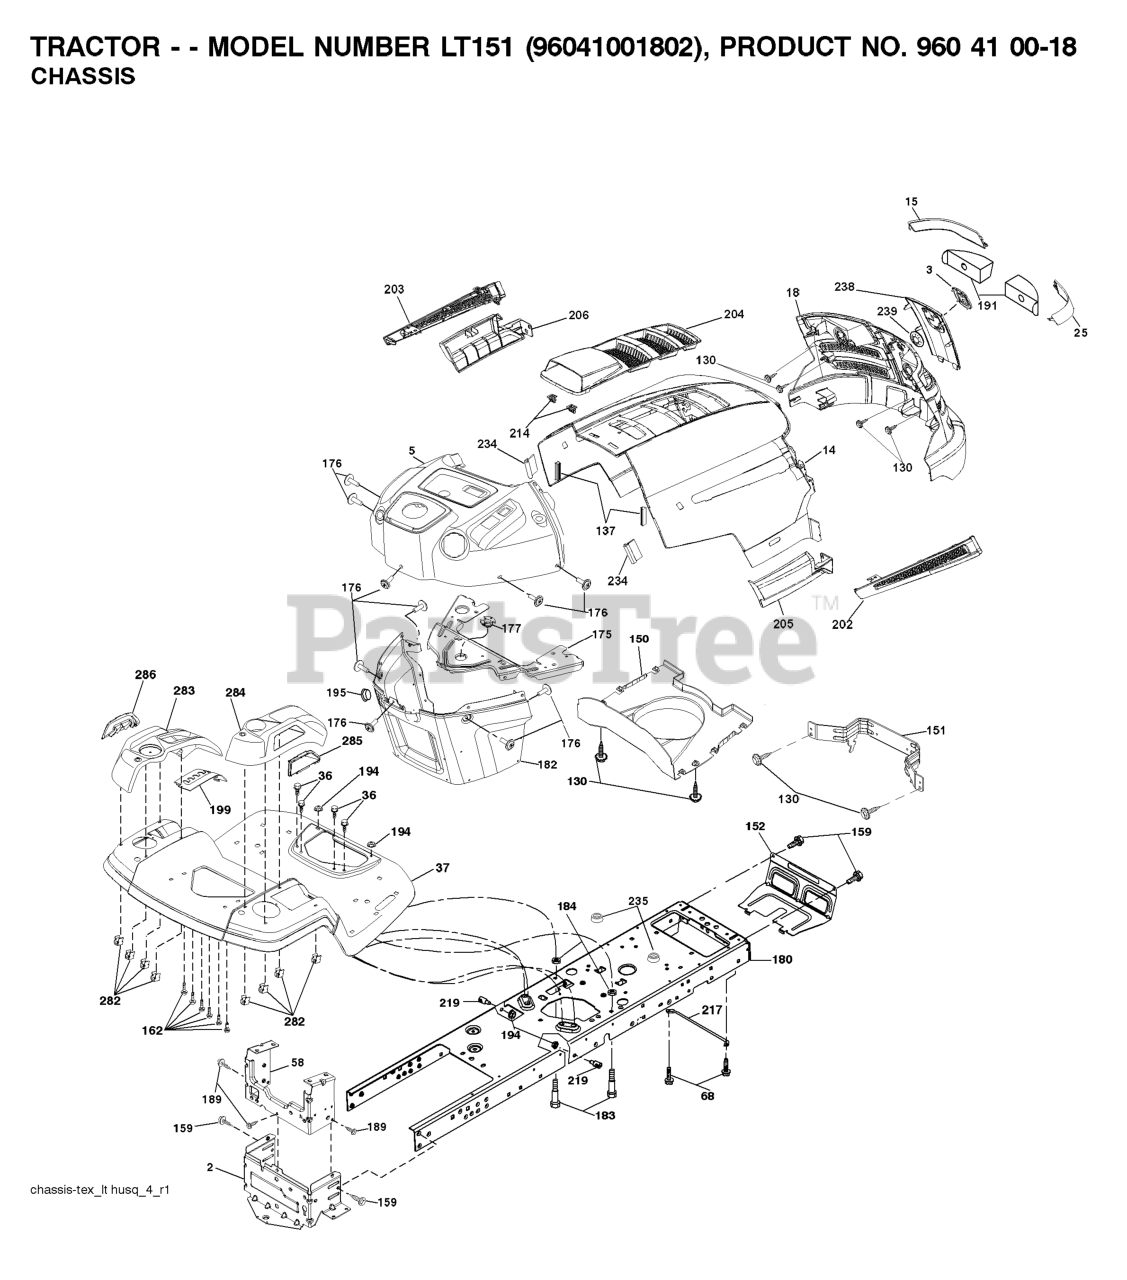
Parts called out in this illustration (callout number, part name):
2	DRAWBAR.UPPER.2PC,LRG.FENDER
3	RP LOGO
5	DASH
14	HOOD
15	LENS.HUSQVARNA LT.LH
18	RP GRILLE/LENS ASM.
25	LENS.HUSQVARNA LT.RH
36	SCREW 5/16"
37	RP FENDER.TLT.FS.W/CPH.422
58	DRAWBAR UPPER 2PC SMALL FENDER
68	Screw 5/16-18 x 1/2 Hex, Self Tapping 5/16-18 x 1/2
130	SCREW
137	BUMPER DASH
151	BRACKET PIVOT
152	SHIELD.BROWNING/DEBRIS
159	SCREW, 3/8-16X3/4
162	SCREW.HI-LO.CONSOLE
175	CROSSMEMBER
176	SCREW.#10-24X5/8.RN.QU
177	BUSHING STEERING
180	CHASSIS.STAMPING.LT/GT
182	DASH.LOWER.PREDATOR LT
183	BOLT.5/16-18X1-1/4 FULL.THREAD
184	NUT.CENTERLOCK.5/16-
189	SCREW
191	INSERT REFLECTIVE
194	NUT LOCK HEX FLANGE 5/16-18
195	PLUG DASH
199	PLATE.DECK.LIFT.HUSQ.LT
202	VENT SIDE HOOD RH
203	VENT SIDE HOOD LH
204	VENT TOP HOOD
205	SKIRT SIDE RH
206	SKIRT SIDE LH
214	CLIP.RETAINER.TINNER.
217	ROD.PIVOT.HOOD
219	STUD.FASTNER.W/ANTI-ROTATE
234	BUMPER.HOOD.TEX.HUSQVARNA
235	SPACER FENDER
238	TRIM
282	CLIP.RETAINER.CONSOLE.LT.HUSQ
283	CONSOLE.DECK.LIFT.HUSQ.N/FR.GR
285	CONSOLE INSERT RH
286	CONSOLE.INSRT.LH.HUSQ.LT.BLACK
287	SCREW 1/4X20
